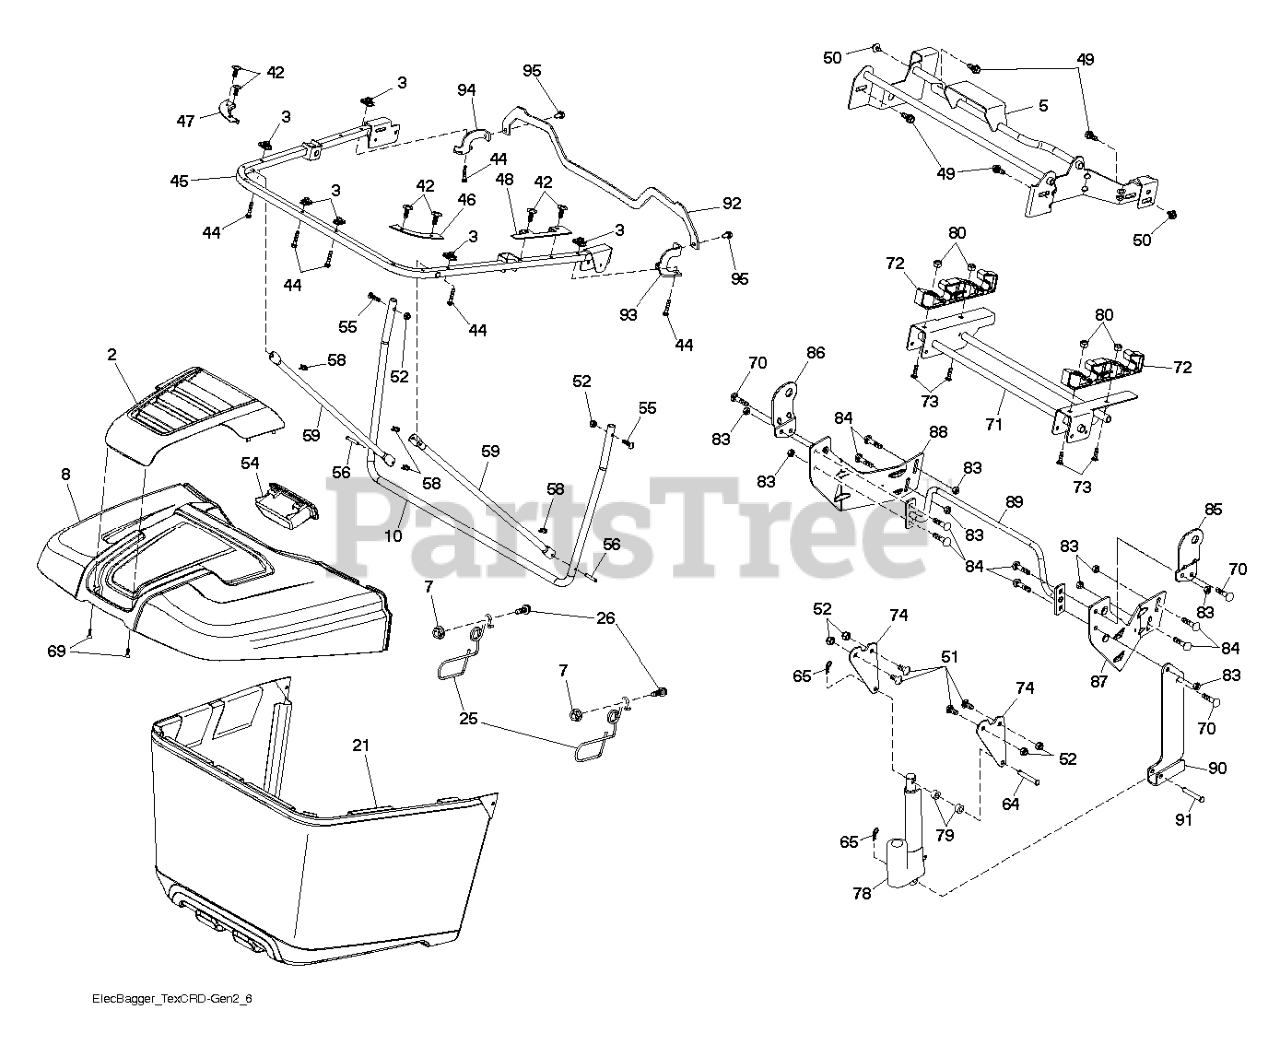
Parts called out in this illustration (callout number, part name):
2	APPLIQUE.BAGGER
3	1/4-20 U NUT
7	NUT T
10	FRAME TEX_CRD_GEN2 BAGGER FRAM
21	BAG FRAME BAGGER ASSEMBLY. HUS
25	LATCH LATCH. BAG. CRD GEN 2
26	SCREW HEX CRT
42	CLIP CHRISTMAS TREE CLIP
45	FRAME TEX_CRD_GEN2 UPPER U FRA
46	CONNECTOR RIGHT BAGGER CORNER
47	CONNECTOR LEFT BAGGER CORNER C
48	BAFFLE BAGGER SIDE CLOSE-OUT
49	BOLT, SHOULDER 5/16-18
50	BOLT.5/16-18UNCX3/4 W/SEMS.BLK
51	BOLT.CARR.SQNK.5/16-18UNC.X3/4
52	NUT.71038.31-18.HEX.NYLOCK
54	HANDLE BAGGER TOP FRONT HANDLE
55	BOLT
56	PIN.CLEVIS.183
58	RETAINER CLIP PM
59	TUBE BAGGER SPREADER TUBE, TEX
65	RETAINER M
69	SCREW,#8.FLAT.HEAD.DRILL.TIP
70	SCREW, 3/8-16X3/4
73	BOLT.CARRIAGE.5/16-18
79	SPACER.NYLON.75" X .4375
80	NUT LOCK HEX FLANGE 5/16-18
83	NUT
84	BOLT D
85	BRACKET.RH.PIVOT.ELE.DUMPX431
86	BRACKET.LH.PIVOT.ELE.DUMPX431
87	BRACKET.RH.MID.SUP.BAG.TEX.CRD
88	BRACKET.LH.MID.SUP.BAG.TEX.CRD
89	WELDMENT.OFFSET.STRUT.SUP.BLAC
90	BRACKET.ELE.DUMP.ACT.BAG.X431
91	PIN.CLEVIS.(.375 X 1.25)
92	BRACKET.PNT.BAGGER.TOP.SUPPORT
93	BRACKET.PNT.RH.SUPPORT.ATTACH
94	BRACKET.PNT.LH.SUPPORT.ATTACH
95	SCREW
